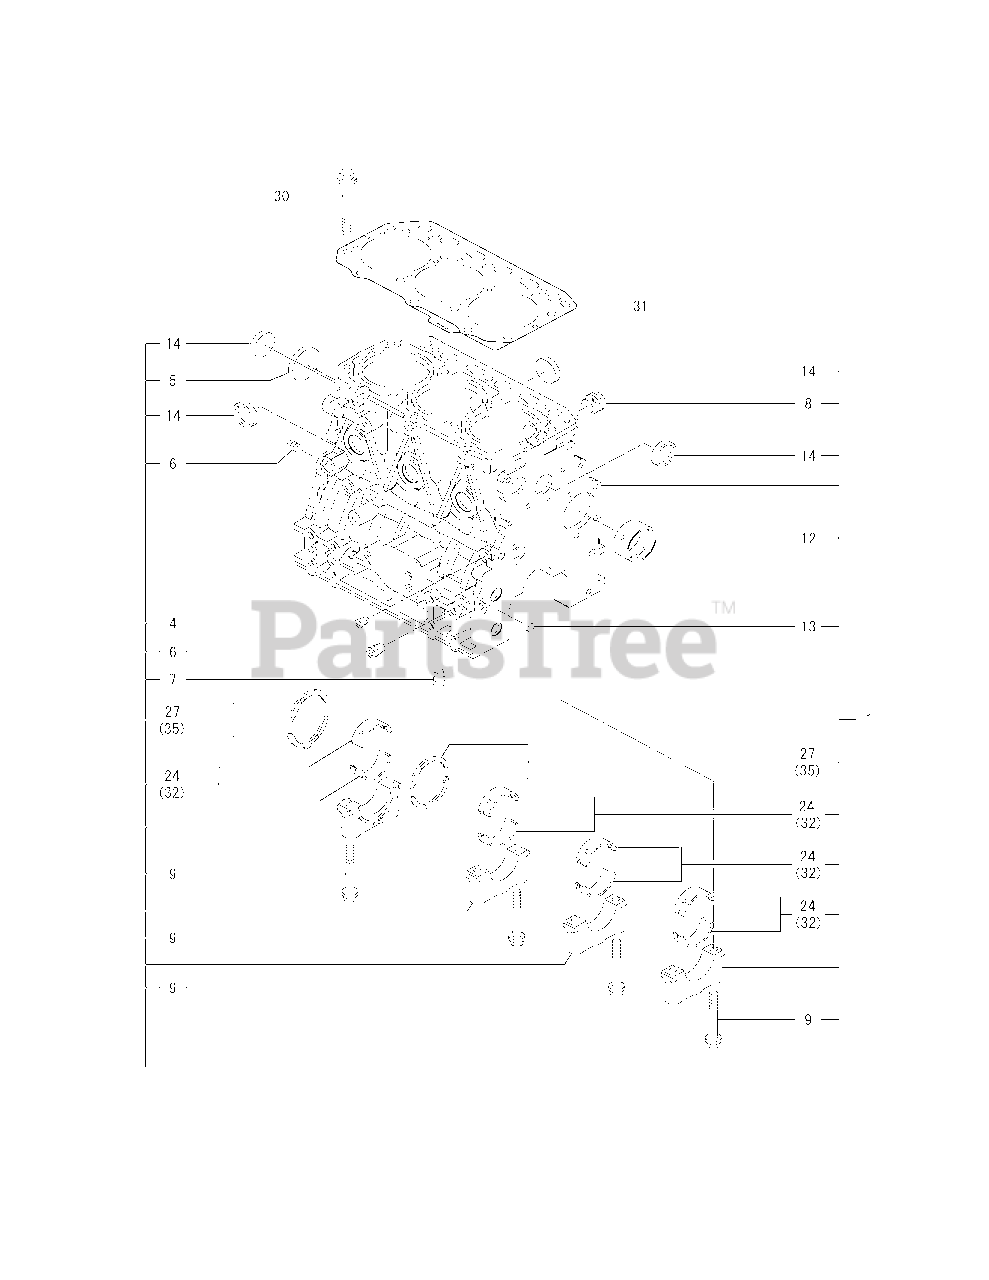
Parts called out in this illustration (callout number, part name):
1	BLOCK ASSY, CYLINDER
9	BOLT, METAL CAP
12	BUSH, CAMSHAFT
14	PLUG 30
24	MAIN BEARING SET
30	STUD, CYL. HEAD
31	GASKET, (NON-ASB.)
32	MAIN METAL US=0.25 UNDER-SIZE
35	METAL,THRUST.25 (2PIE) OVER-SIZE
